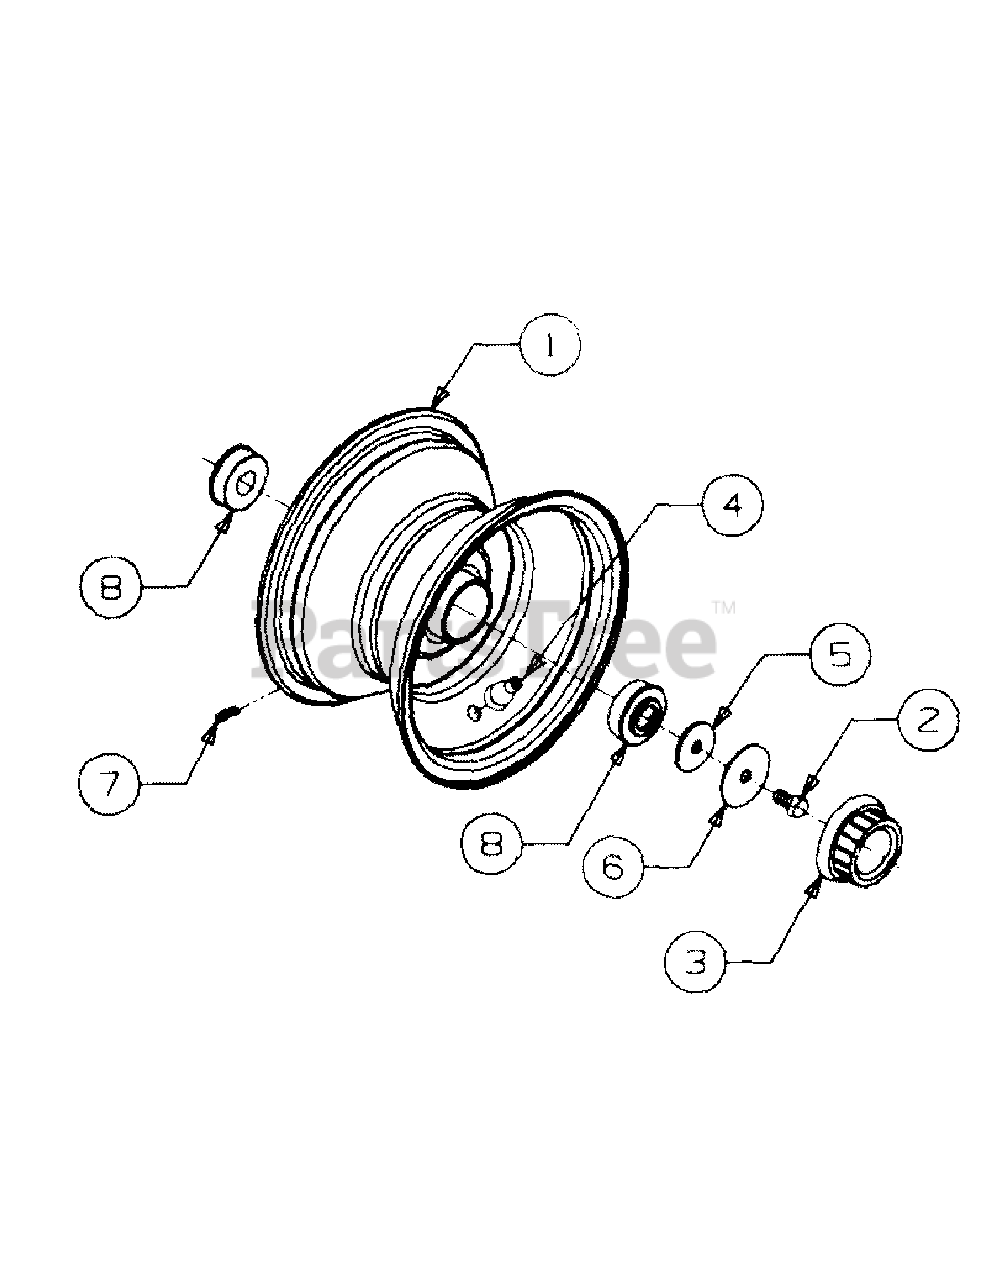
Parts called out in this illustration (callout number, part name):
2	Bolt, Hex Patch, 3/8-16 x .75 Lg GR5
3	Cap, Hub
4	Valve, Tubeless Air
5	Washer, Flat, .406 x 1.5 x .110 Thk
6	Washer, Flat, .406 x 1.92 x .06 Thk
7	Fitting, Grease
8	Bearing, Ball
